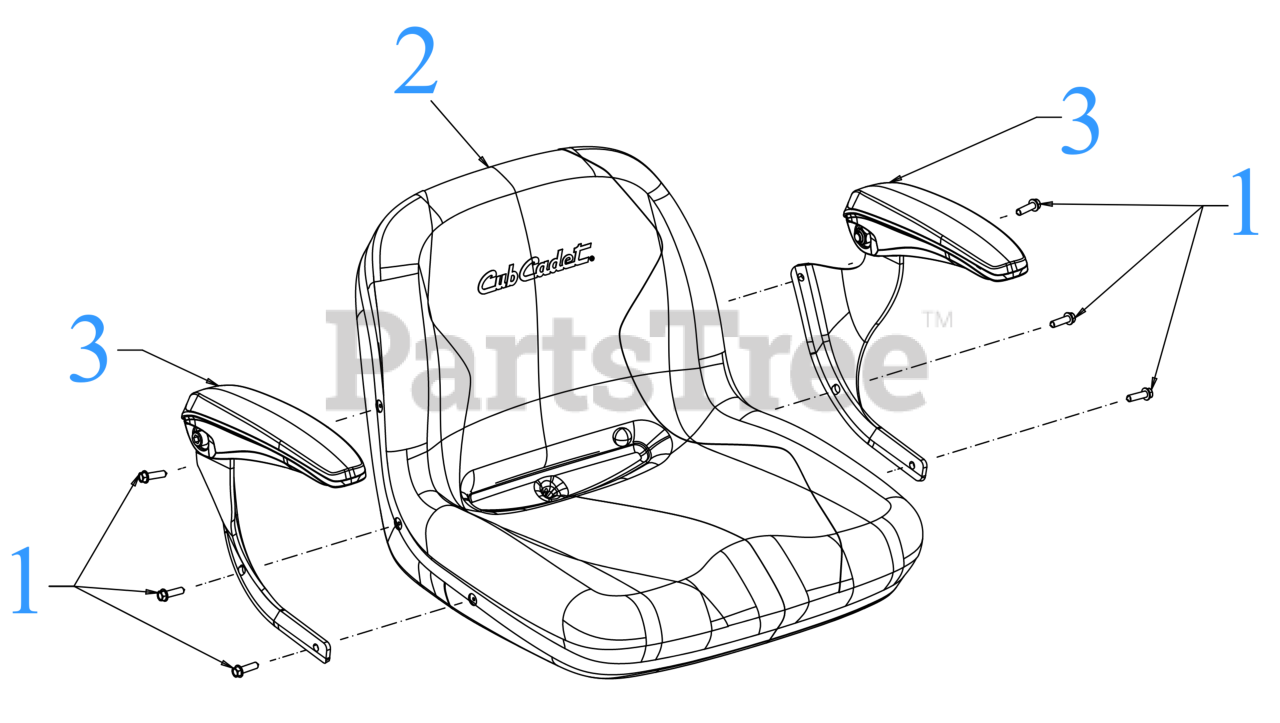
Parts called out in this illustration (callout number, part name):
1	SCREW 1/4-14X 1.00
2	SEAT (HI BACK/CUB)
3	ARM REST KIT (06027/06100)
